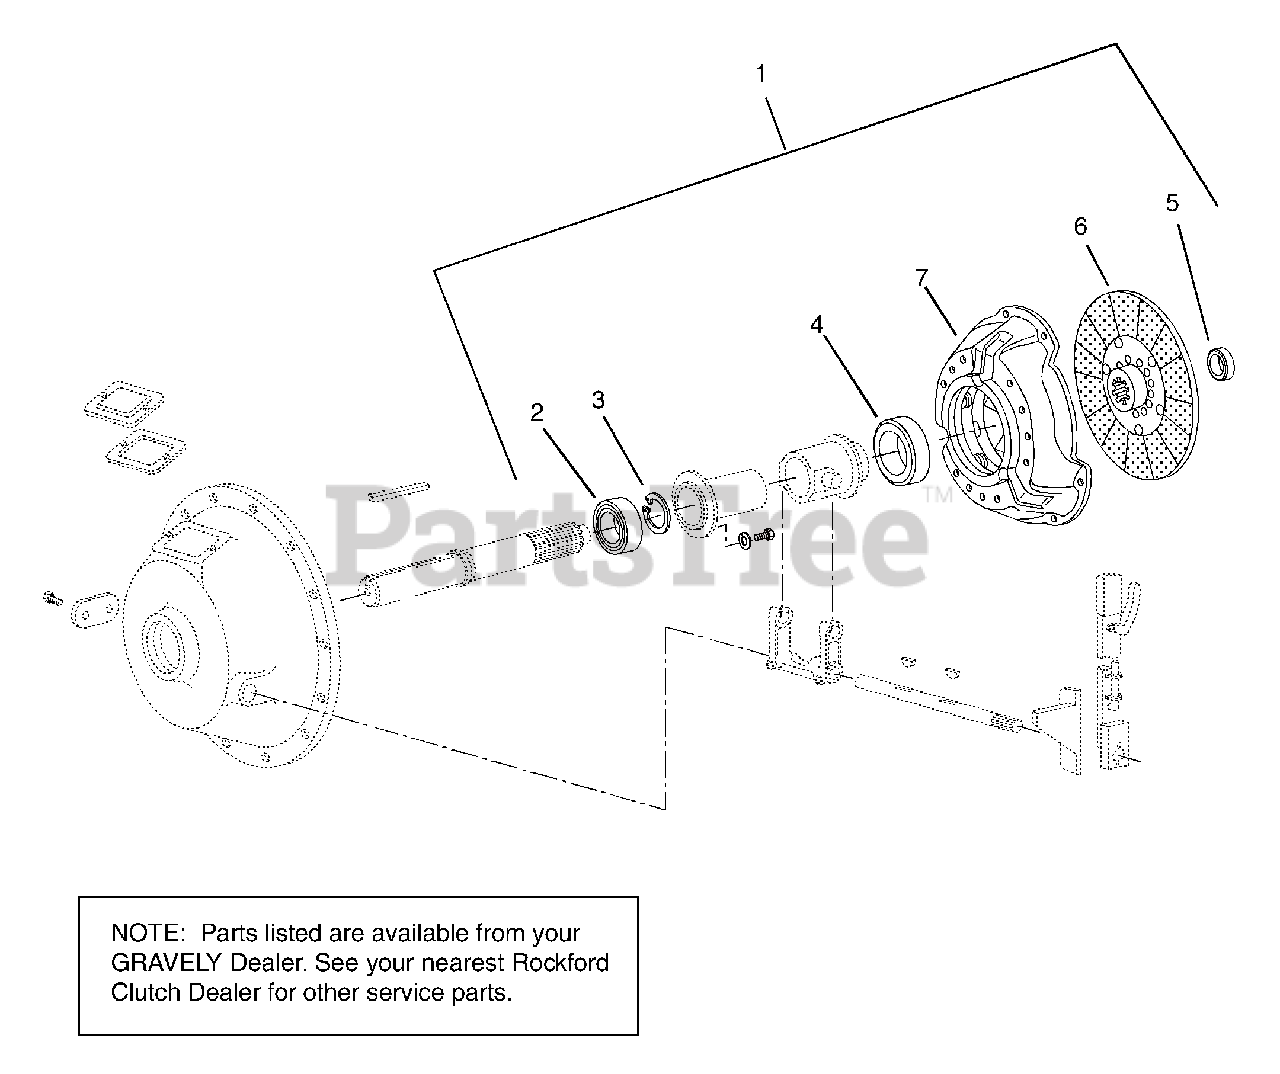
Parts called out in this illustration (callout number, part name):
1	Clutch Assembly
2	Bearing-Ball Main
3	Ring-Retainer-External
4	Ball Bearing-Thrust
5	Ball Bearing-Pilot
6	Plate-Friction
7	Plate-Pressure/Cover
